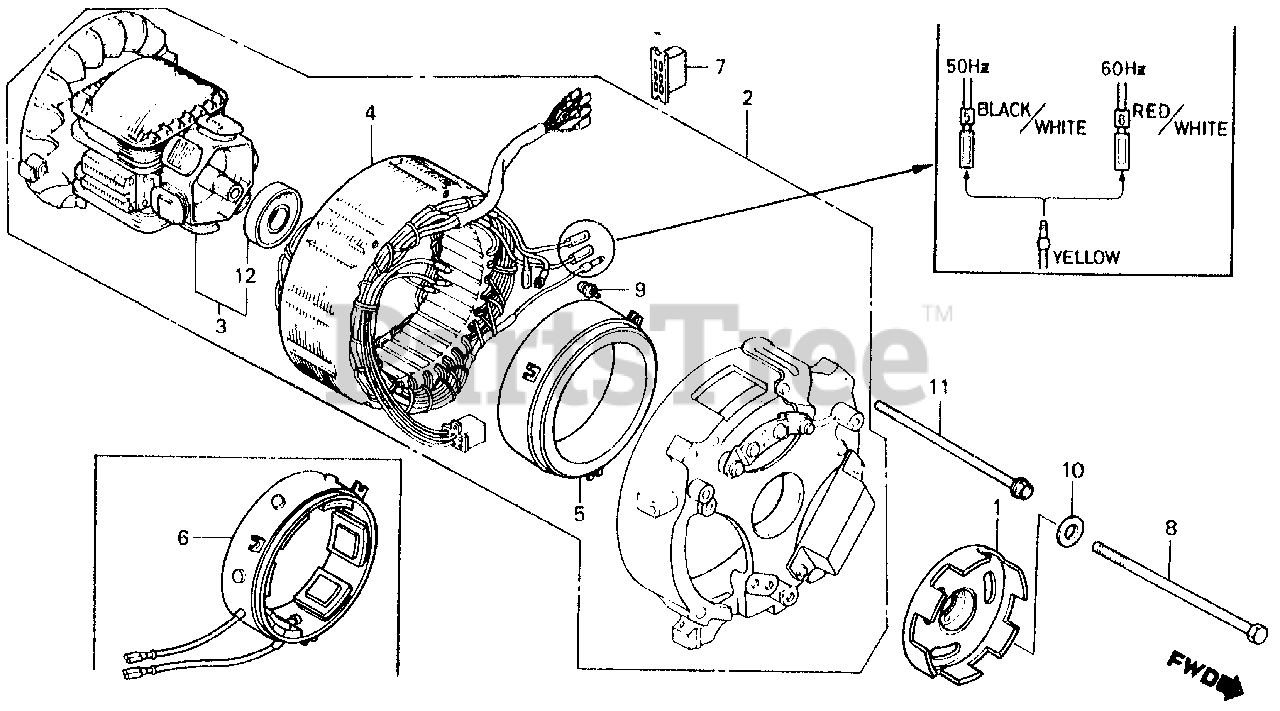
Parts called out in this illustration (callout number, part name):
1	PULLEY, STARTER (NOT AVAILABLE)
2	ALTERNATOR ASSY.
4	STATOR ASSY.
5	EXCITER ASSY. (NOT AVAILABLE)
7	CONNECTOR, MALE (6 POLE)
8	BOLT, HEX. (8X120)
9	SCREW, TAPPING (5X12)
10	WASHER, PLAIN (8MM)
11	BOLT, FLANGE (6X120)
12	BEARING, RADIAL BALL (6002)
